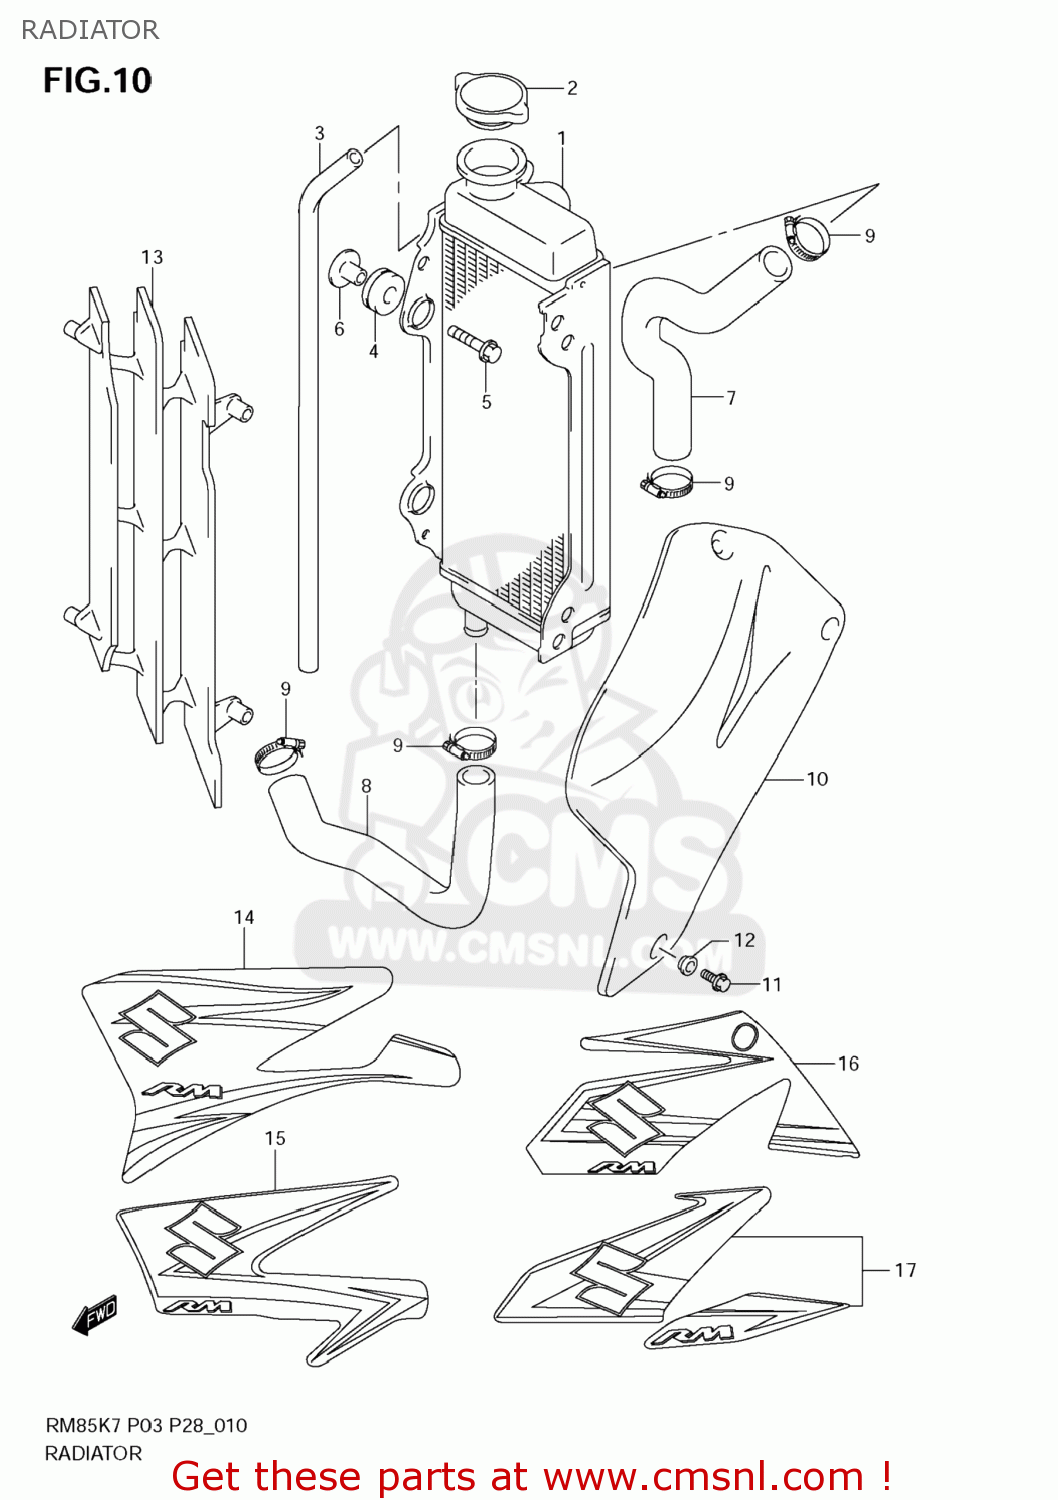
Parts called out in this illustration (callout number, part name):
1	RADIATOR,WATER
2	CAP COMP,RADIATOR
3	HOSE(5X8X1000)
4	CUSHION,RADIATOR LWR
5	BOLT(6X25)
6	SPACER(6.5X10.5X14.1)
7	HOSE,RADIATOR INLET
8	HOSE,RADIATOR OUTLET
9	CLAMP
10	COVER,RADIATOR,L(YELLOW)
11	BOLT(6X12)
12	WASHER
13	LOUVER,RADIATOR
14	TAPE,RADIATOR COVER,L
15	TAPE,RADIATOR COVER,L
16	TAPE,RADIATOR COVER,L
17	TAPE,RADIATOR COVER,L
